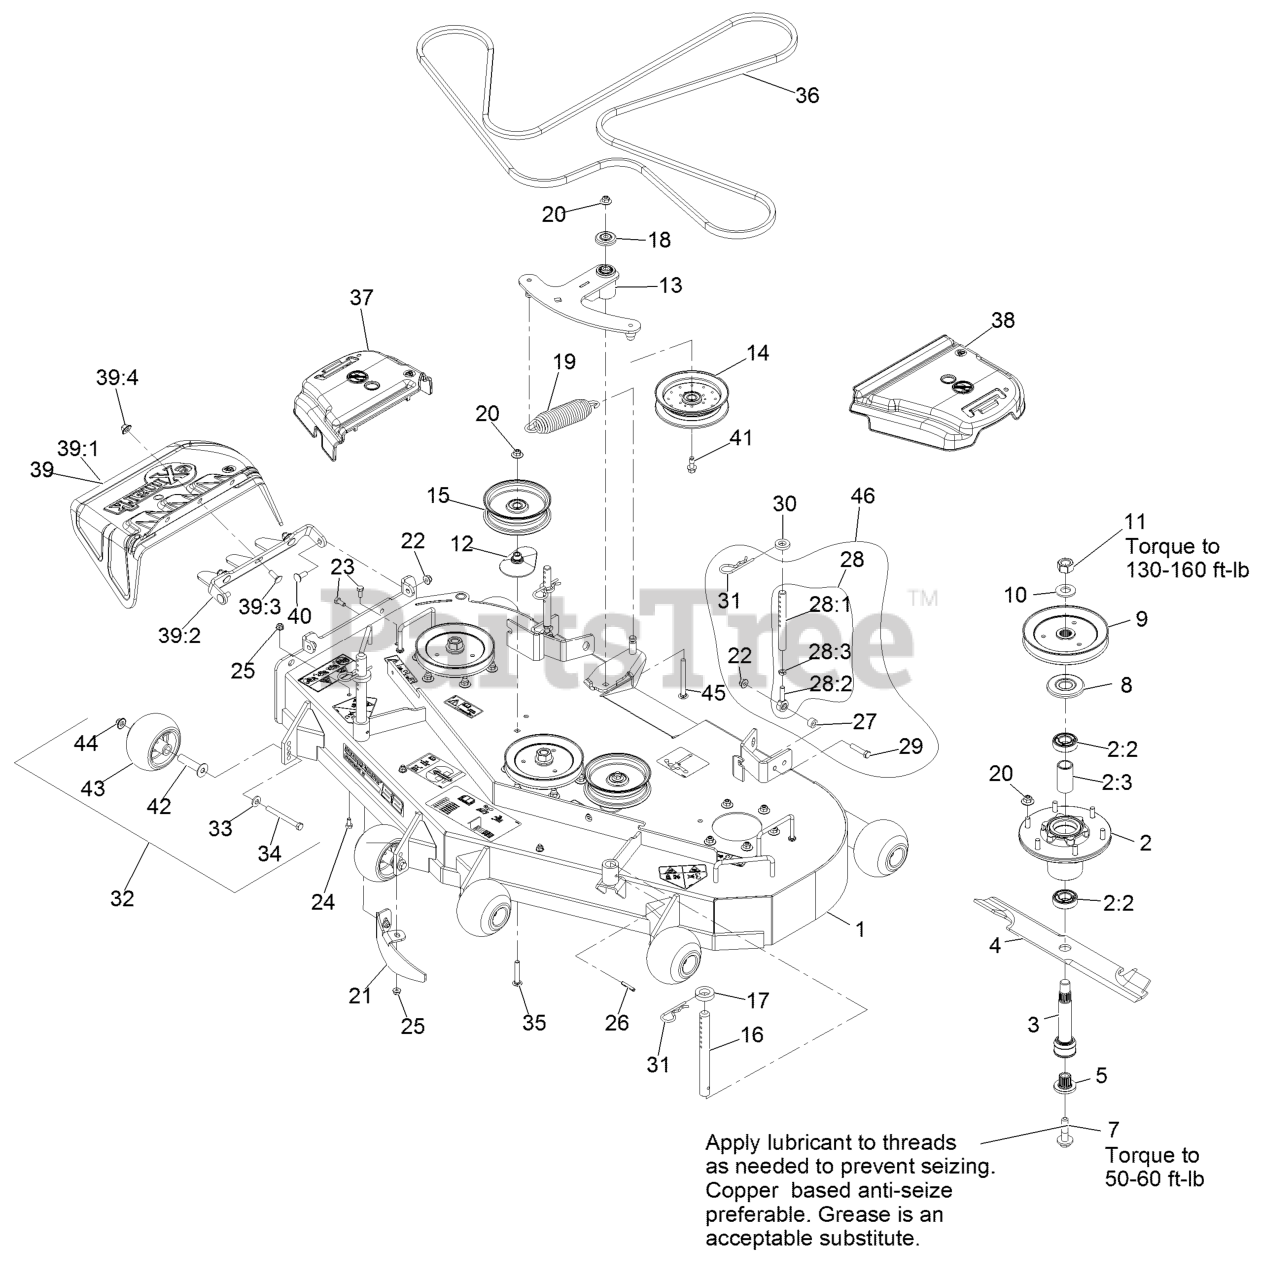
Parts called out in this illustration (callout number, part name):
1	ASM, DECK W/ DECALS, 52"
2	ASM-CUTTER HSG WITH BEARINGS
2:2	BEARING-BALL
2:3	SPACER-BEARING
3	ASM-SPINDLE AND SEAL
5	BUSHING,SPLINED
7	SCREW,SEMS 1/2-20 X 2.19
8	GUARD,BEARING TOP .989
9	SHEAVE,BLADE DRIVE 6.50
11	NUT-HEX
12	SPACER-PULLEY
13	ASM, DECK IDLER
15	IDLER-PULLEY, FLAT
16	ROD,DECK SUPPORT
17	SPACER-DECK SUPPORT
18	GUARD-TOP
19	SPRING-EXTENSION
20	Nut-Nyloc 3/8-16 Flg
21	BAFFLE, DOGLEG
22	NUT-HF, NI
23	SCREW-HH
24	SCREW-HH
25	NUT-HF, NI
28:1	LINK,SUPPORT
28:2	BALLJOINT
28:3	NUT-HJ
29	SCREW-HH
31	PIN,HAIR COTTER
32	KIT, ANTI-SCALP ROLLER
33	WASHER-BELLEVILLE
34	SCREW-HH 3/8-16 X 3 3/4 GR 8
35	BOLT-CARR, SHORT NECK
36	BELT, DECK
37	COVER-BELT, RH
38	COVER-BELT, LH
39	ASM, DISCHARGE CHUTE
39:1	CHUTE,DISCHARGE
39:2	BRACKET, DISCHARGE CHUTE
39:3	SCREW-CARR
39:4	Nut-Nyloc 3/8-16 Flg
40	SCREW-CARR
41	SCREW-HFH
42	AXLE, ROLLER
43	ROLLER-SCALP, ANTI
44	Nut-Nyloc 3/8-16 Flg
45	SCREW-CARR
46	KIT,SUPPORT LINK W/PIN
